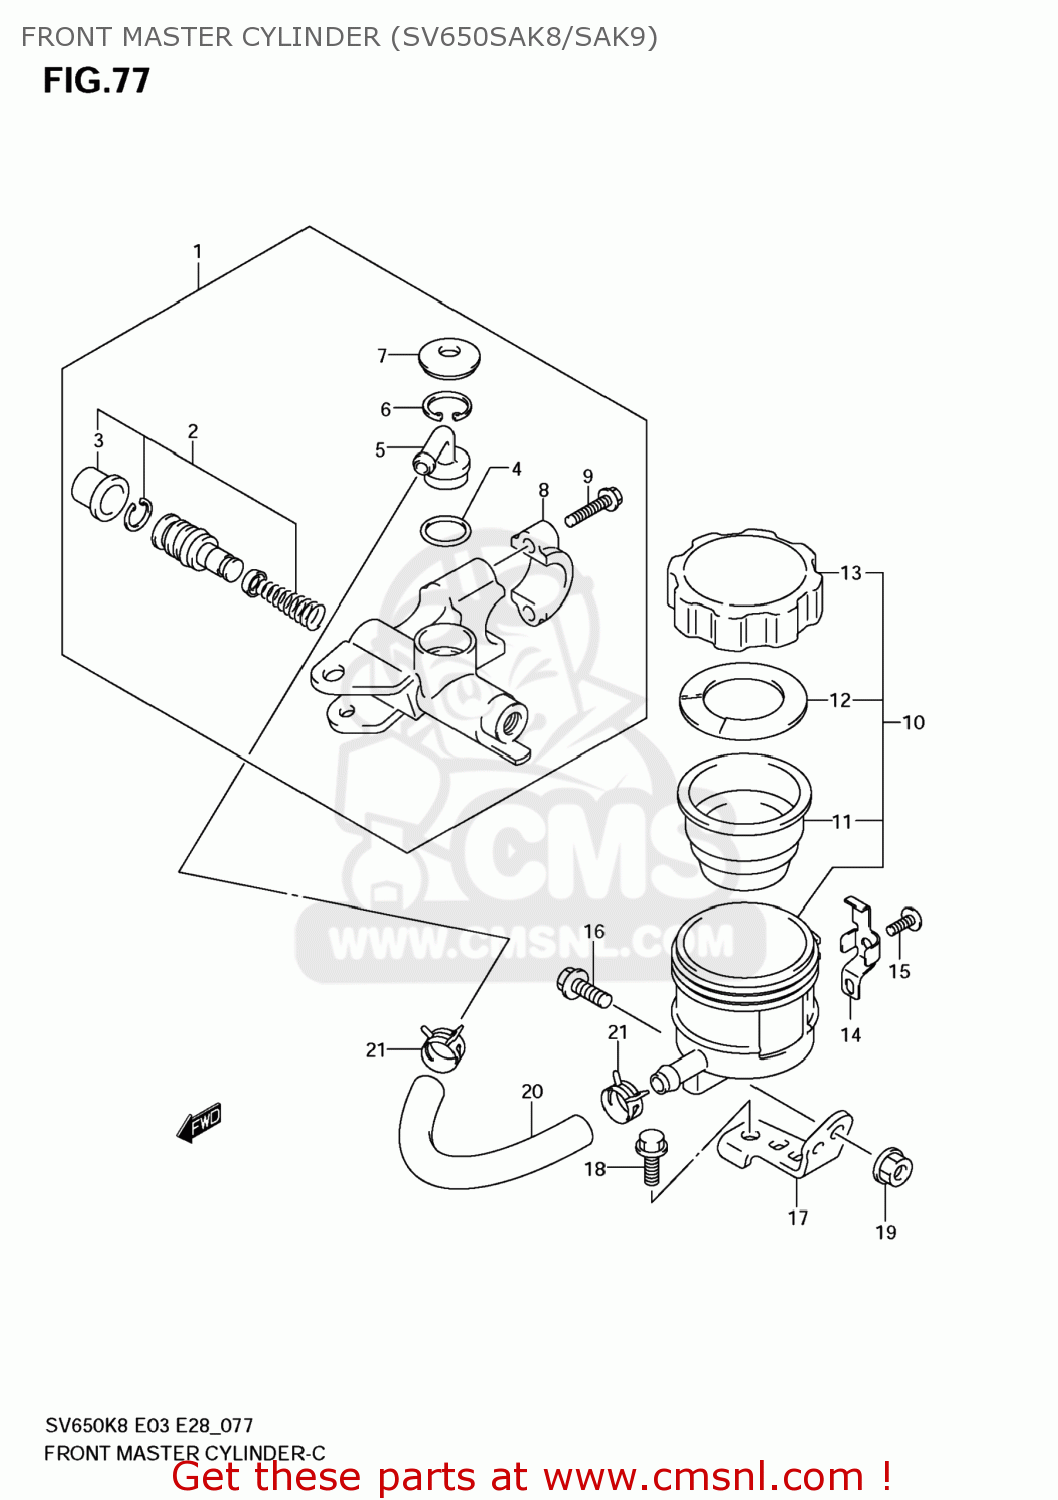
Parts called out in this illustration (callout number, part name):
1	CYLINDER ASSY,FR MASTER
2	PISTON & CUP SET
3	BOOT
4	O RING
5	CONNECTOR
6	CIRCLIP
7	COVER,DUST
8	HOLDER
9	BOLT(6X22)
10	TANK ASSY,RESERVOIR
11	DIAPHRAGM
12	PLATE,DIAPHRAGM
13	CAP
14	PLATE,RESERVOIR TANK CAP
15	SCREW
16	BOLT
17	BRACKET,RESERVOIR TANK
18	BOLT
19	NUT
20	HOSE,FR RESERVOIR TANK
21	CLAMP,RESERVOIR TANK FR
